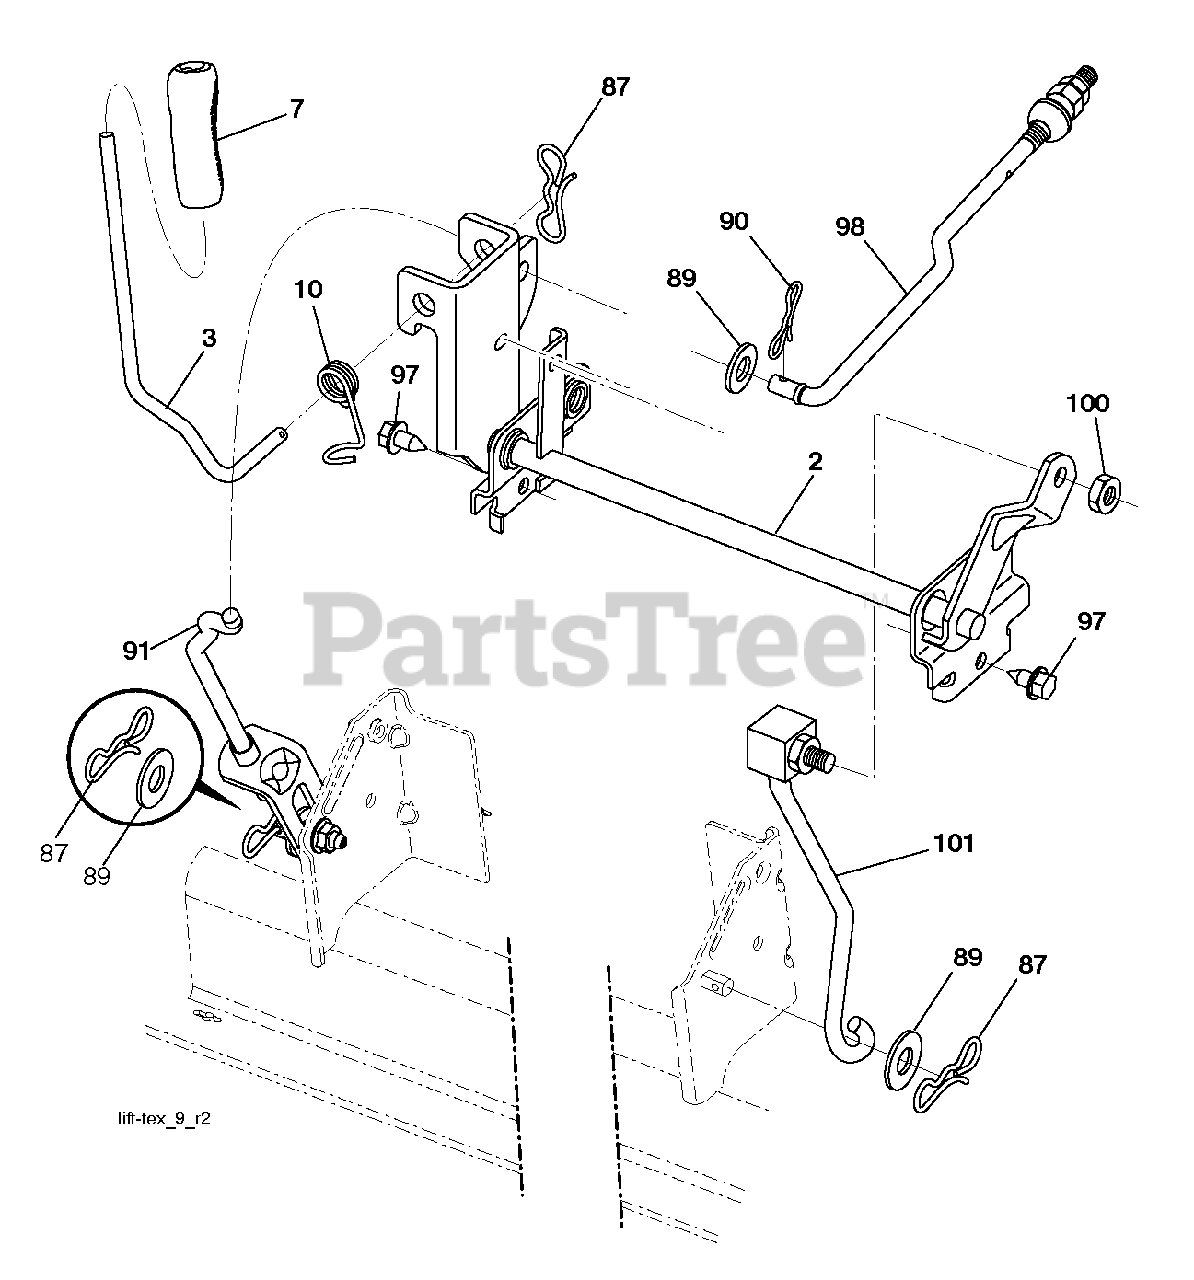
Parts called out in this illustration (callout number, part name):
2	SHAFT.ASM.CROSS.LIFT
3	LEVER.LIFT.HANDLE.LT
7	GRIP.HANDLE.LIFT.PVC.BLACK
10	SPRING.TORSION.LIFT.HANDLE
87	PIN.COTTER.7/16.BOW TI.
89	WASHER.CLEAR.ZINC
90	PIN.COTTER.5/16.BOW TI
91	LINK.ASM.LIFT.REAR
97	SCREW, 3/8-16X3/4
98	LINK.ASM.SUSP.FRONT.MW
100	LOCKNUT
101	LINK.ASM.LIFT.FIXE.38/42/46"
